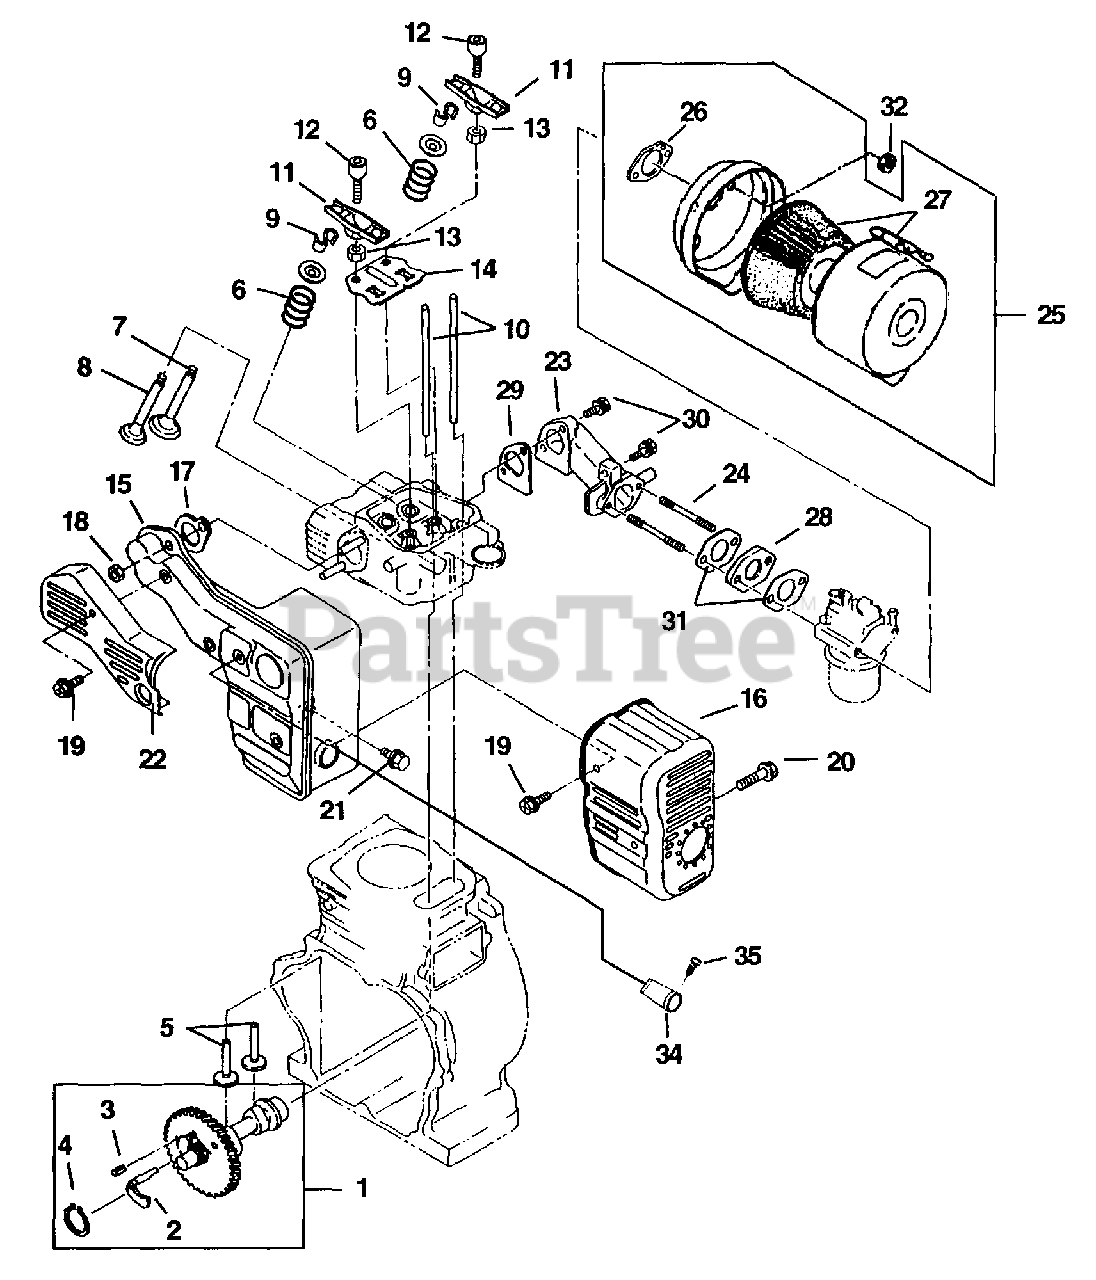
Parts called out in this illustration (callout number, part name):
1	Camshaft
2	Release lever
3	Spring pin
4	Snap ring
6	Valve spring
7	Intake valve
8	Exhaust valve
9	Collet valve
10	Push rod
11	Rocker arm
12	Pivot bolt
14	Guide plate
16	Muffler cover
17	Muffler gasket
18	Nut M8
19	Tapping bolt M8
20	Tapping bolt M8
21	Bolt & washer
22	Exhaust pipe cover
23	Intake pipe
25	Air cleaner
26	Packing
28	Insulator
29	Intake pipe gasket
30	Bolt & washer M8 x 28
31	Insulator gasket
32	Nut & washer M6
34	Spark arrestor
35	Tapping screw
